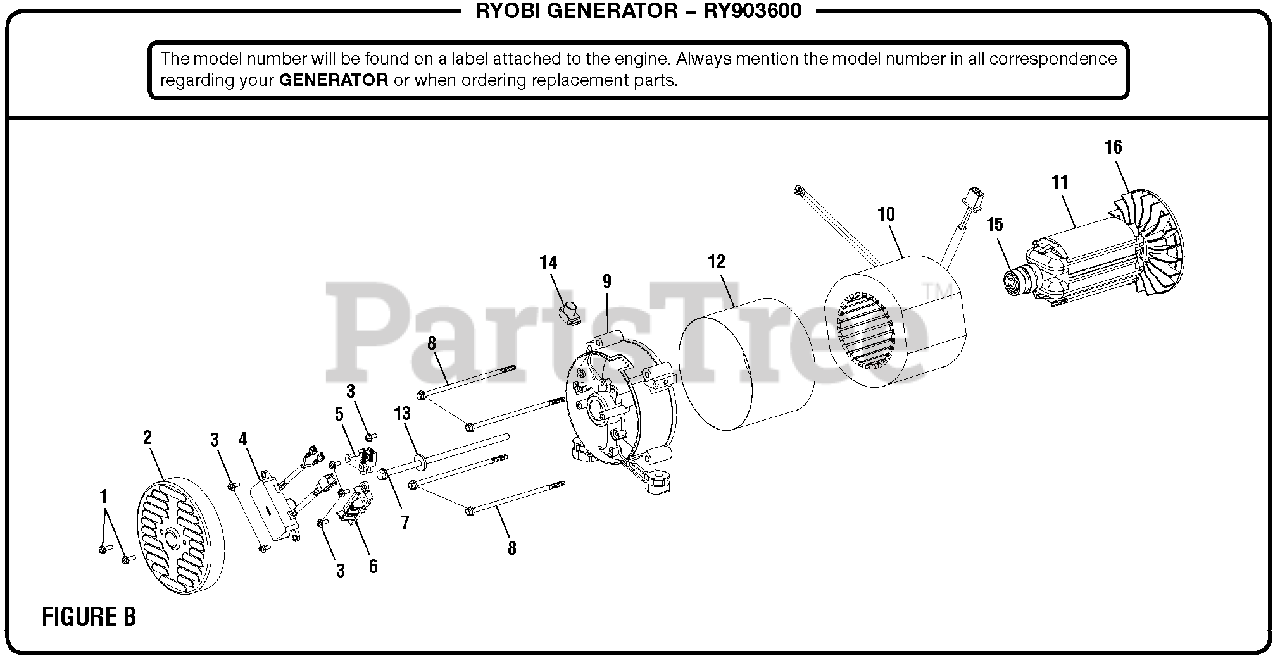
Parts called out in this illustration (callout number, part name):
1	Bolt (M5 x 12 mm, Hex Flange Hd.)
2	Brush Cover
3	Bolt (M5 x 16 mm, Hex Flange Hd.)
4	Automatic Voltage Regulator
5	Brush Assembly
6	Terminal Block
7	Rotor Bolt
8	Stator Bolt
9	Bearing Housing
10	Stator Assembly
11	Rotor Assembly
13	Rotor Washer
14	Rubber Boot
15	Ball Bearing
